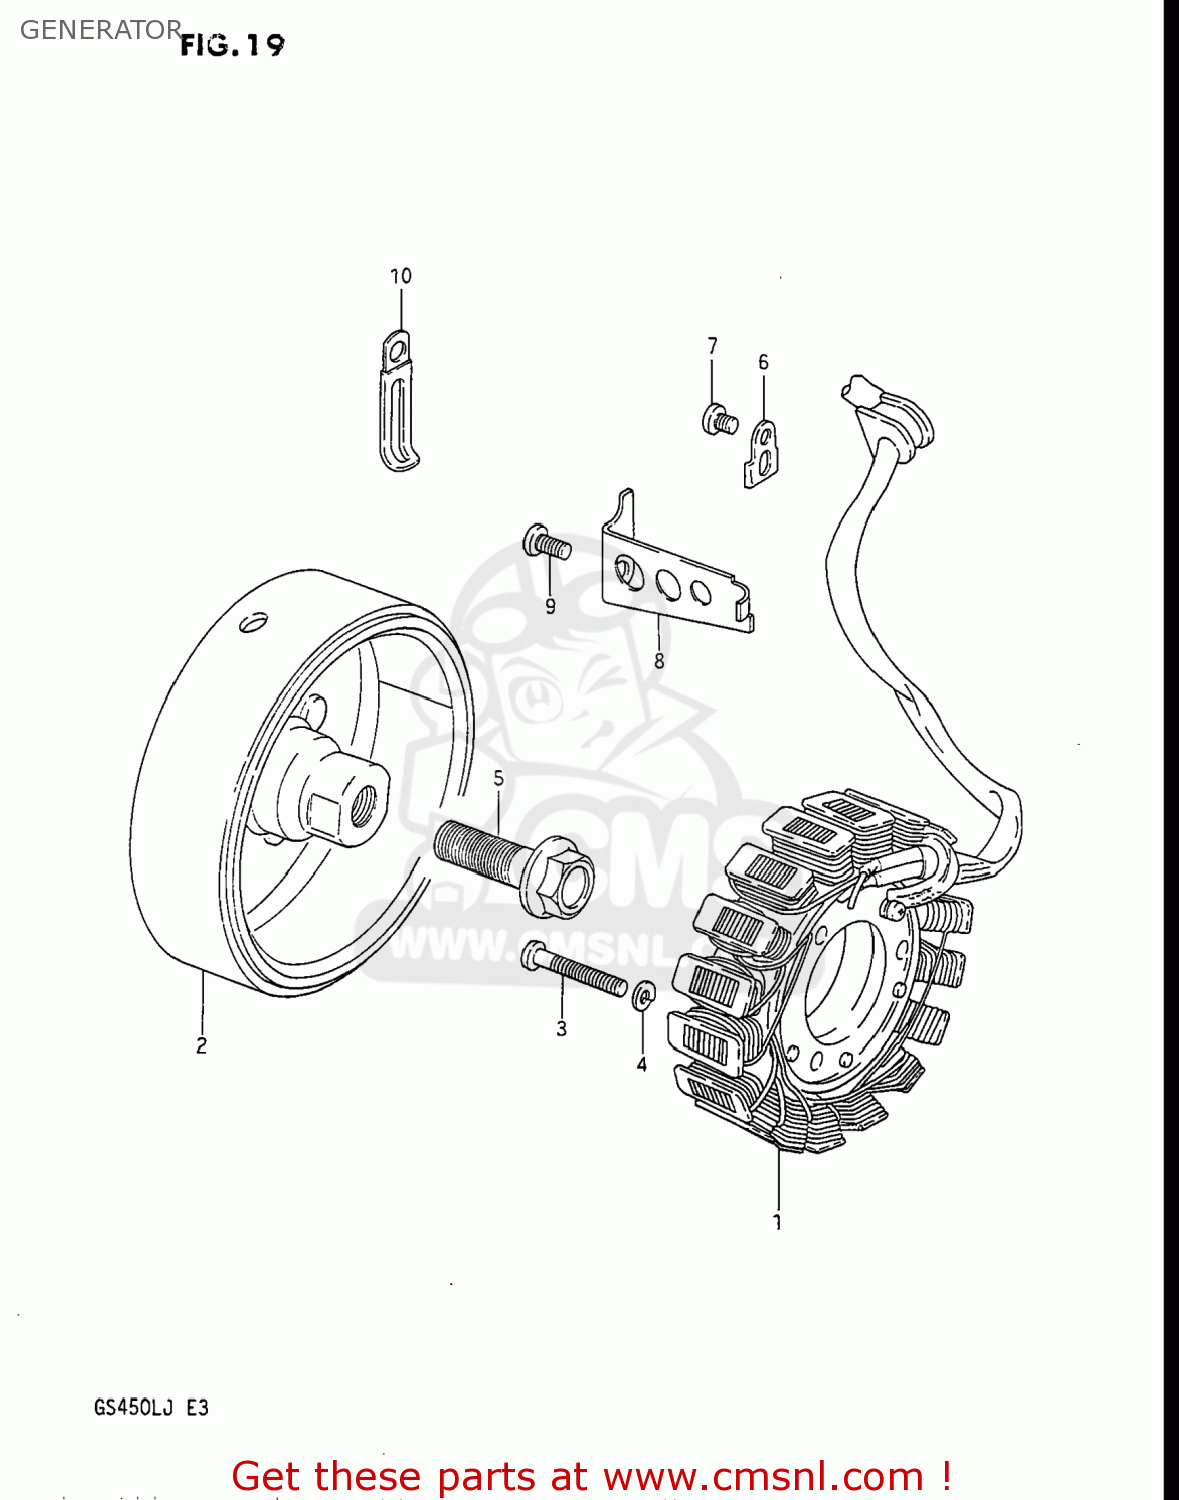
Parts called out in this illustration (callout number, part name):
1	STARTER ASSY
2	ROTOR ASSY
3	SCREW
4	LOCK WASHER
5	BOLT(12X40)
6	CLAMP,GENERATOR LEAD WIRE
7	SCREW
8	CLAMP,GENERATOR LEAD WIRE
9	SCREW
10	CLAMP L:35
